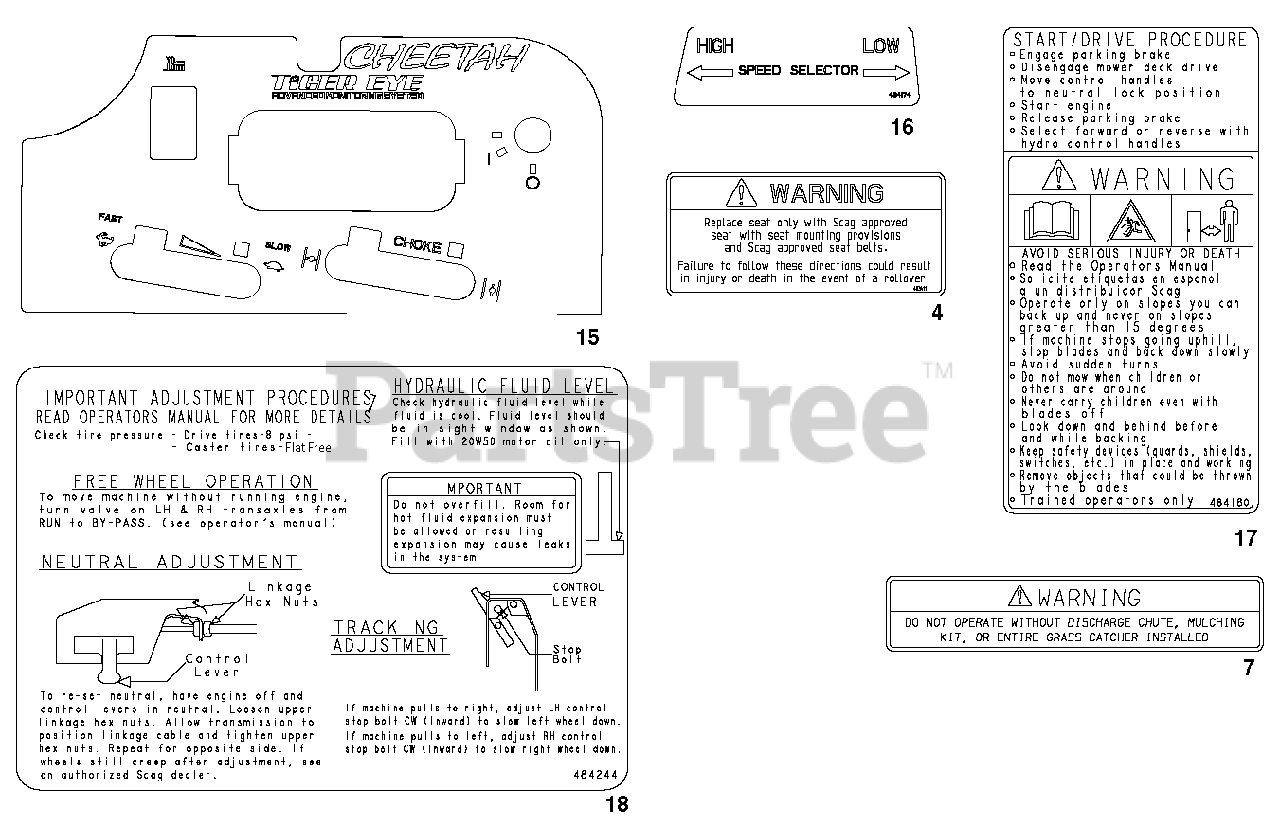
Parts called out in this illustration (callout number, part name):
4	Decal, Seat Replacement
7	Decal, Warning
15	Decal, Instrument Panel - SCZ
15	Decal, Instrument Panel - SCZ - EFI
16	Decal, Speed Control
17	Decal, Start / Drive
18	Decal, Adjustments - SCZ
